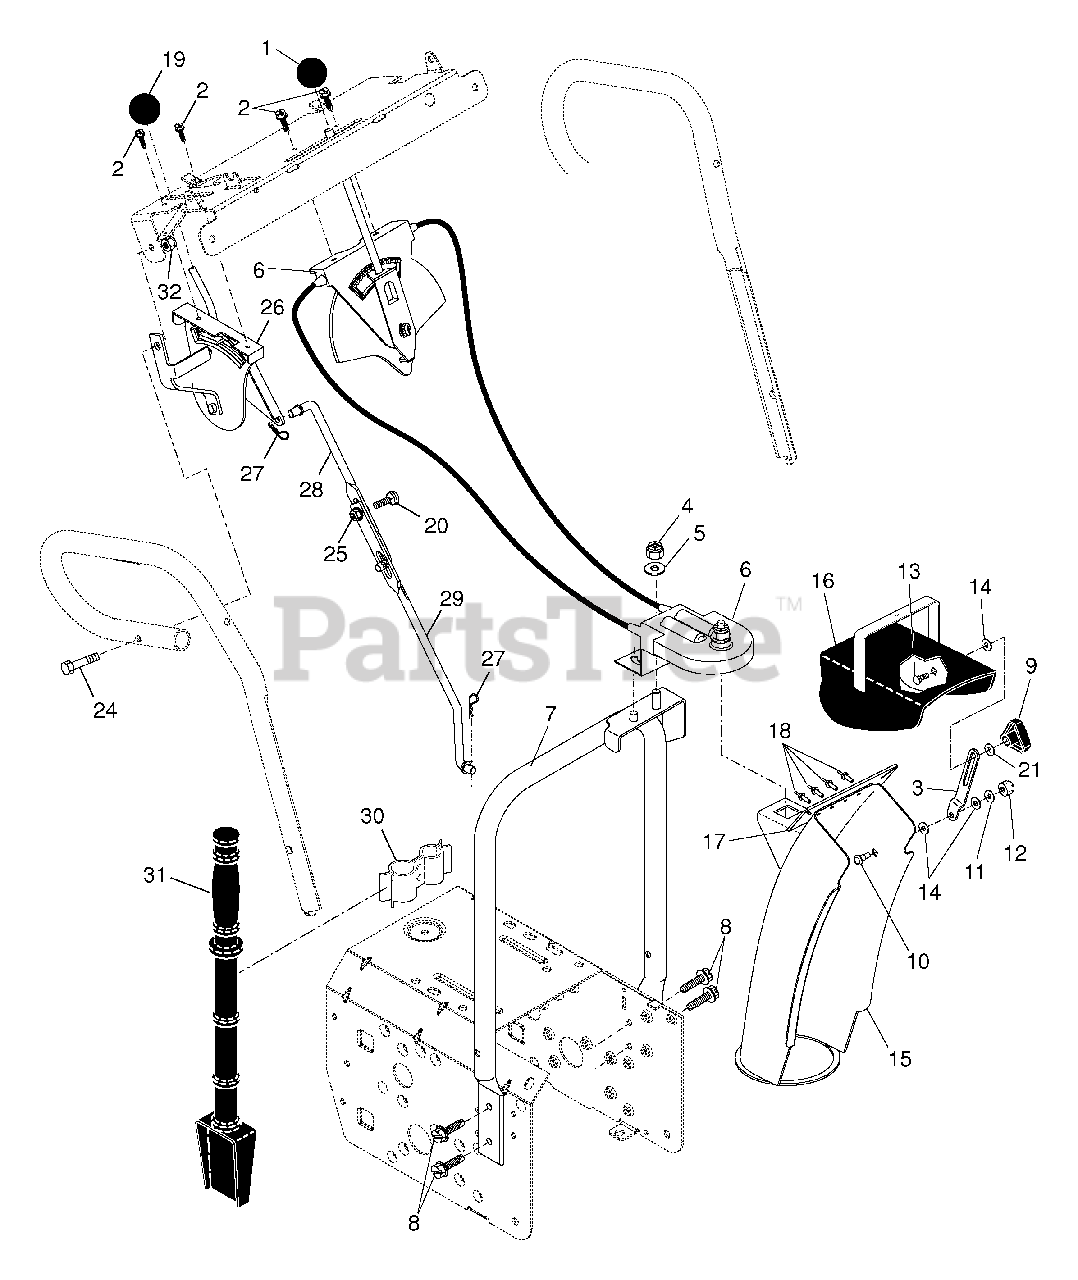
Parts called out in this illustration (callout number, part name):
1	Knob, Lever
2	Screw #10-24 x 5/8
3	Strap, Slotted
4	Nut, Lock 3/8-16
5	Washer, Flat 3/8
6	Control Assembly, Chute Rotater
7	Support, Pivot
8	Screw, Hex Head 5/16-18 x 3/4
9	Knob, Deflector
10	Bolt, Shoulder
11	Washer, Flat 1/4
12	Nut, Lock 1/4-20
13	Bolt, Carriage 5/16-18 x 5/8
14	Washer, Nylon
15	Chute Assembly
16	Deflector Assembly
17	Seal, Deflector
18	Rivet, Blind
19	Knob, Speed Control Lever
20	Bolt, Carriage 5/16-18 x 3/4
21	Washer, Flat 5/16
24	Screw, Hex Head 5/16-18 x 1-3/4
25	Nut, Lock 5/16-18
26	Lever Assembly, Speed Control
27	Retainer, Hairpin
28	Rod, Upper, Speed Control
29	Rod, Lower, Speed Control
30	Clamp, Clean-Out Tool
31	Tool, Clean-Out
32	Nut, Lock 5/16-18
